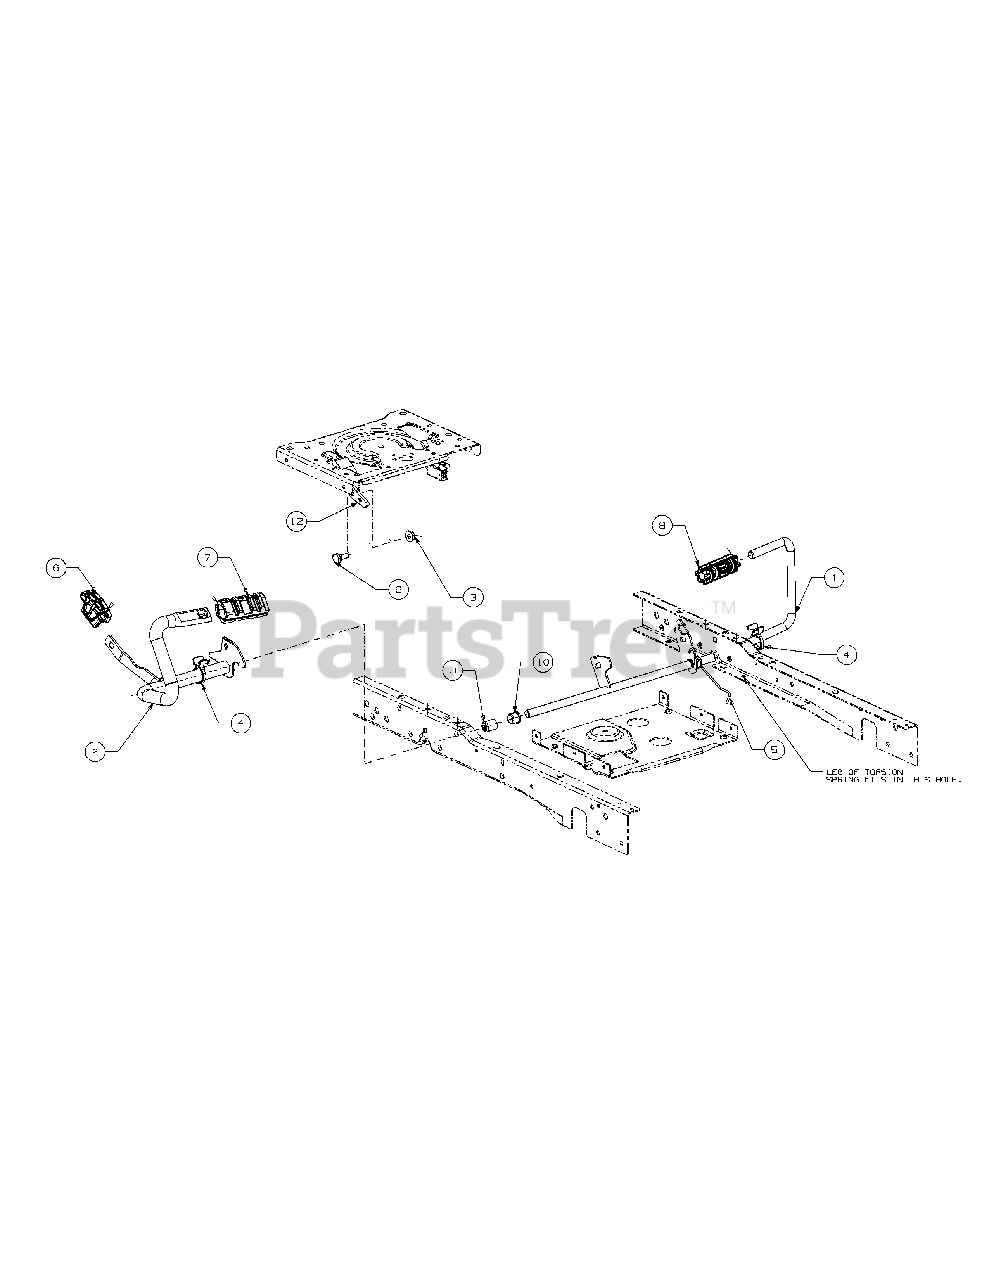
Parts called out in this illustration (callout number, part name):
1	Pedal Asm:Brake
2	Pedal Asm:Fwd & Rev:Tube
2	Pad-Foot
3	Nut-Flange Lock
4	Clip-Pedal Nylon
5	Spring-Torsion
6	Pad-Reverse Pedal
7	Pad-Forward Pedal
8	Pad-Brake Pedal
9	Bolt:Shldr:.500 X .270:3/8-16
10	Bearing-Flg .63X.84X.71
11	Bearing-Sleeve
12	Latch-Cruise
